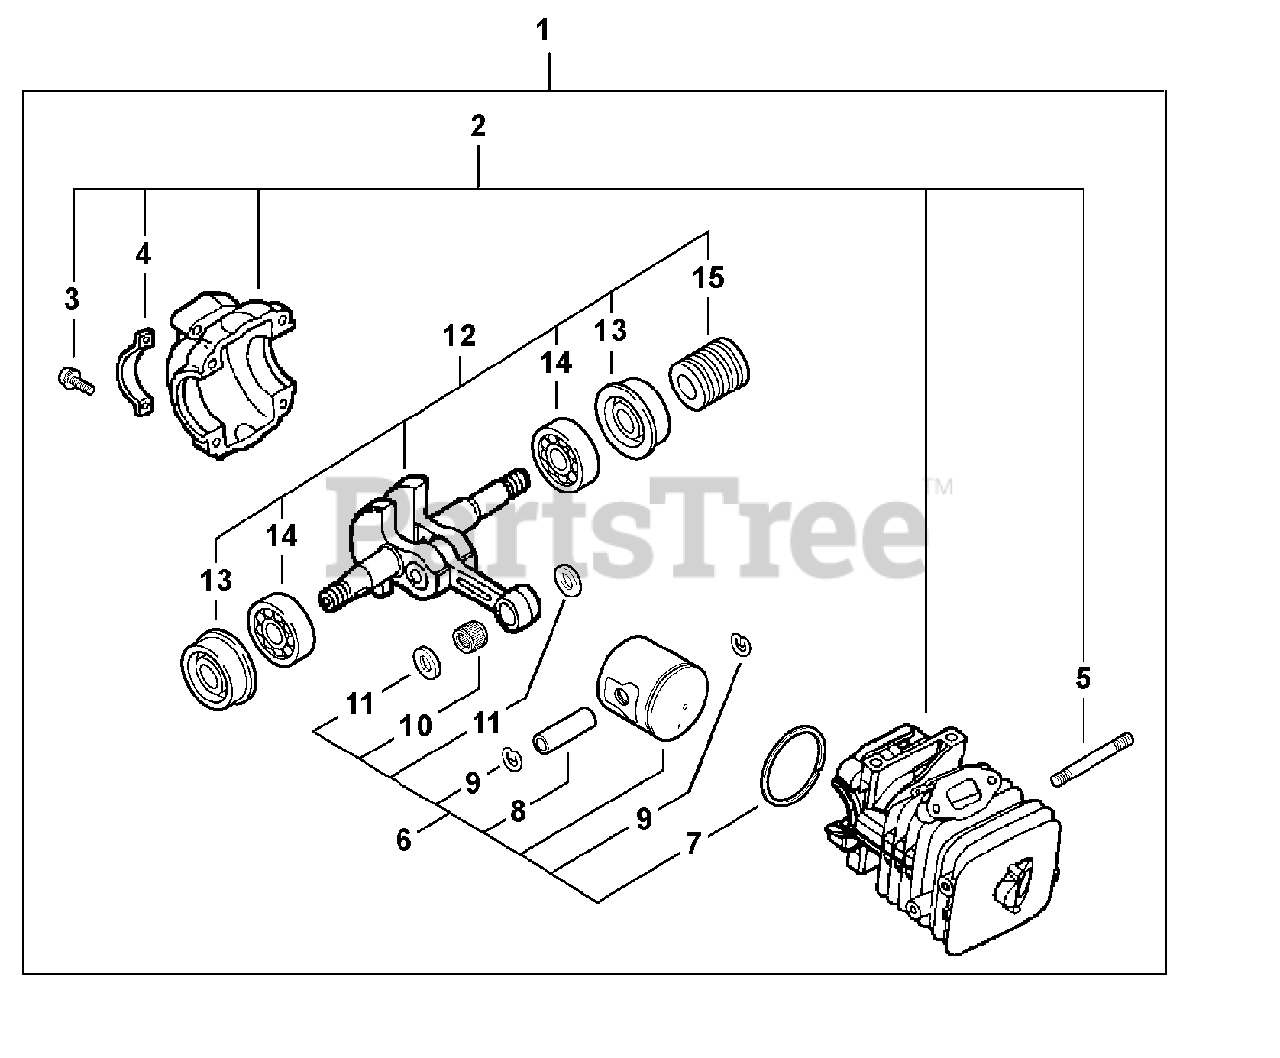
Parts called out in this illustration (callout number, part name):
1	SHORT BLOCK -- SB1085
2	CRANKCASE KIT
3	SCREW - 5X25
4	BRACKET, CRANKCASE
6	PISTON KIT
7	RING, PISTON
8	PIN, PISTON
9	RING, RETAINING
10	BEARING, NEEDLE - 8
11	SPACER, PISTON
12	CRANKSHAFT ASSY
13	SEAL, OIL - 12
14	BEARING, BALL - 6201
15	GEAR - WORM
